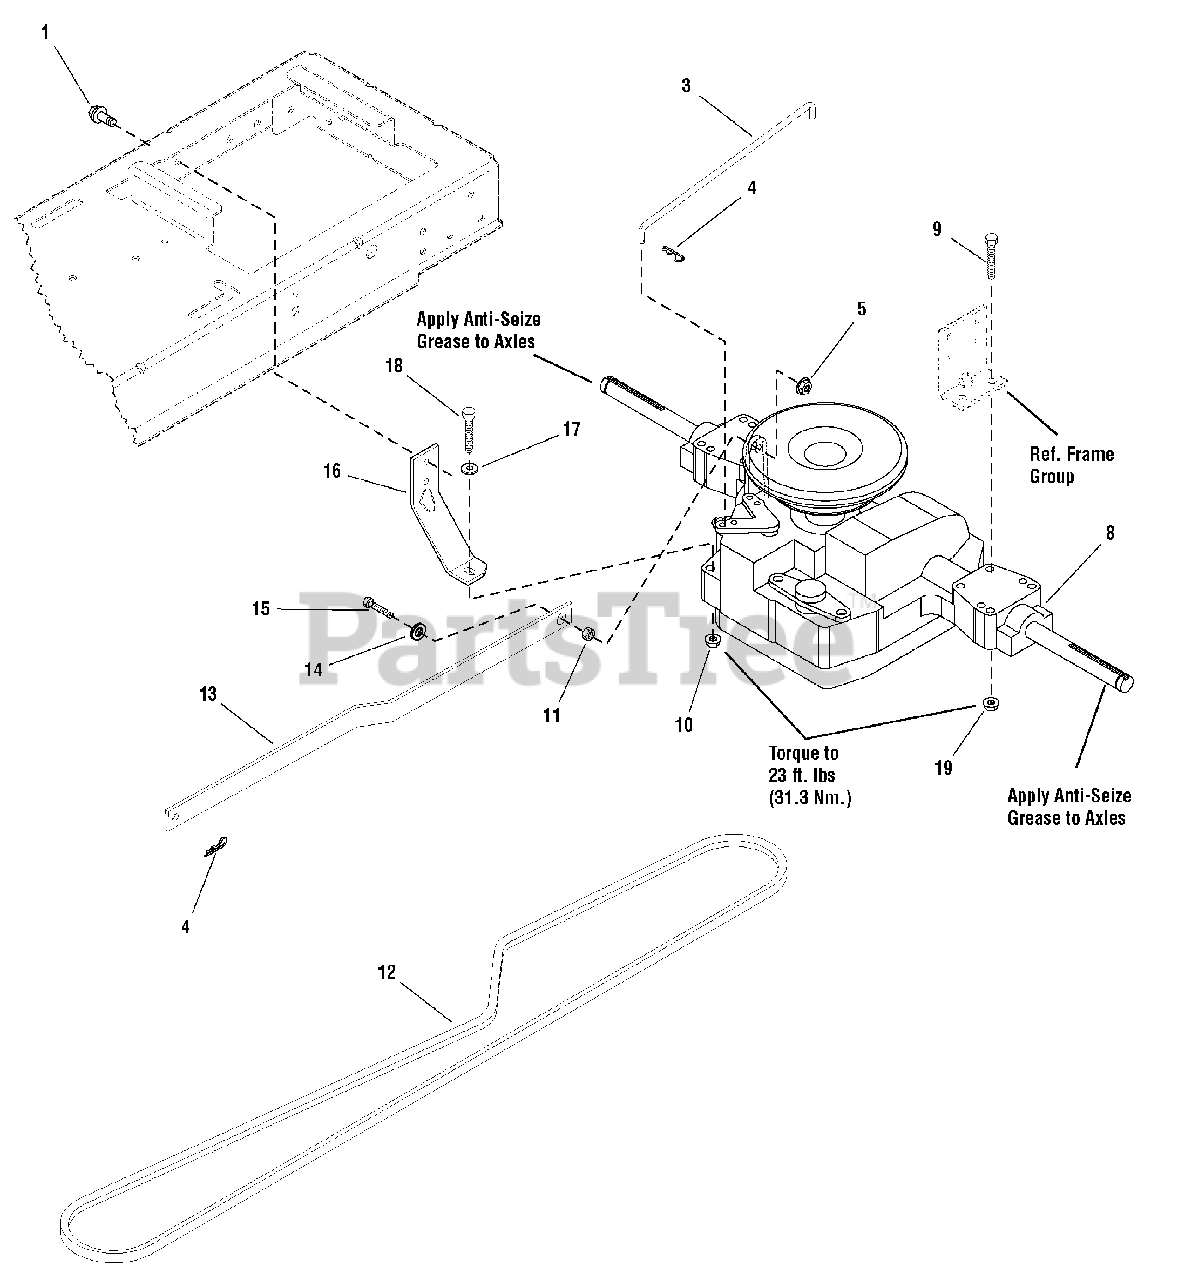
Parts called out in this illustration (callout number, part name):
1	CAPSCREW, Hex Head, Taptite, 5/16-18 x 3/4
3	ROD, Bypass, 11.44 LG
4	PIN, Quick
5	NUT, Hex Flange, ESNA, 5/16-18
8	TRANSMISSION ASSEMBLY, K46BP
8	TRANSMISSION ASSEMBLY, K46BL
9	SCREW, Hex Head Flange Lock, 5/16-18 x 2-1/2
10	NUT, Hex Flange, ESNA, 5/16-18
11	SPACER
12	V-BELT, Drive Belt, Aramid/Kevlar 89.25" EL HA
13	ARM, Control
14	WASHER, Flat, 5/16
15	CAPSCREW, Hex Head, 5/16-18 x 1
16	STRAP, Torque
17	WASHER, Plain, 5/16
18	CAPSCREW, Hex Head, 5/16-18 x 1-3/4
19	NUT, Hex, Flange Whizlock, 5/16-18
